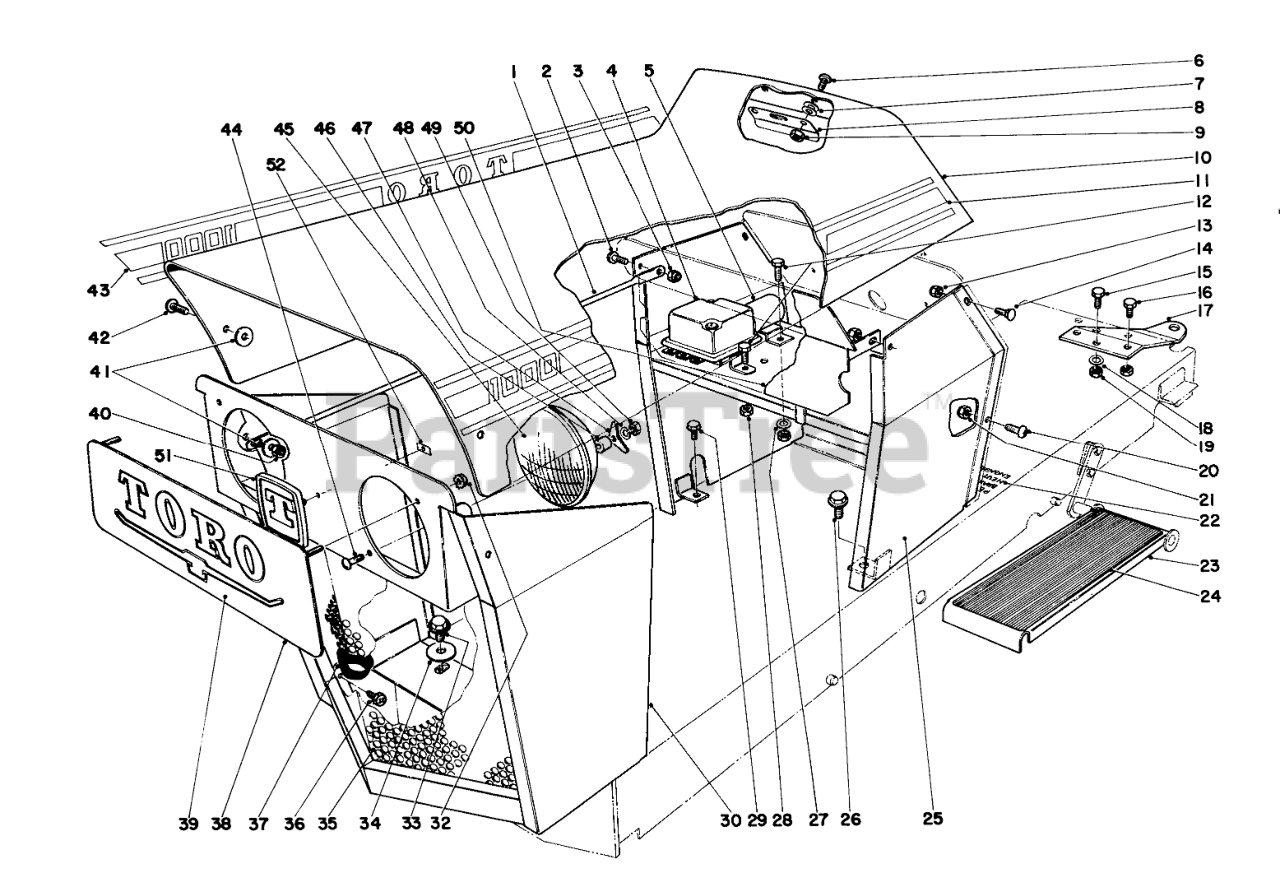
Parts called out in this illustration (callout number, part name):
1	Rod Hood Support
2	Capscrew Socket Head
4	Voltage Regulator
5	Solenoid
6	Screw, Phillips
7	Washer
8	Hood Latch
11	Decal Side L.H. 10 H.P.
12	SCREW-HH
14	SCREW-CARR
15	SCREW-HH
16	SCREW-HH
17	Chassis Hitch
18	WASHER-FLAT
20	Capscrew Socket Head
21	Nut
22	Decal Clutch Release
23	Foot Rest
24	Pad Foot Rest
25	Battery Support
26	Sems Screw
27	WASHER-FLAT
29	Screw-HH
30	Grille Frame W.A.
33	Sems Screw
34	Washer
35	Grille
36	Self Tapping Screw
37	Grommet
38	Head Light Cover
39	Decal Cover Plate
40	Nut
41	Washer
42	Capscrew Socket Head
43	Side Hood R. H. 10 H.P.
44	SCREW-SRH
45	HEAD LAMP
46	Spacer
47	Clip 960
48	WASHER-LOCK/SP
49	NUT-HEX
50	Heat Deflector
51	Logo Plate Recoil
52	Timmerman Nut
